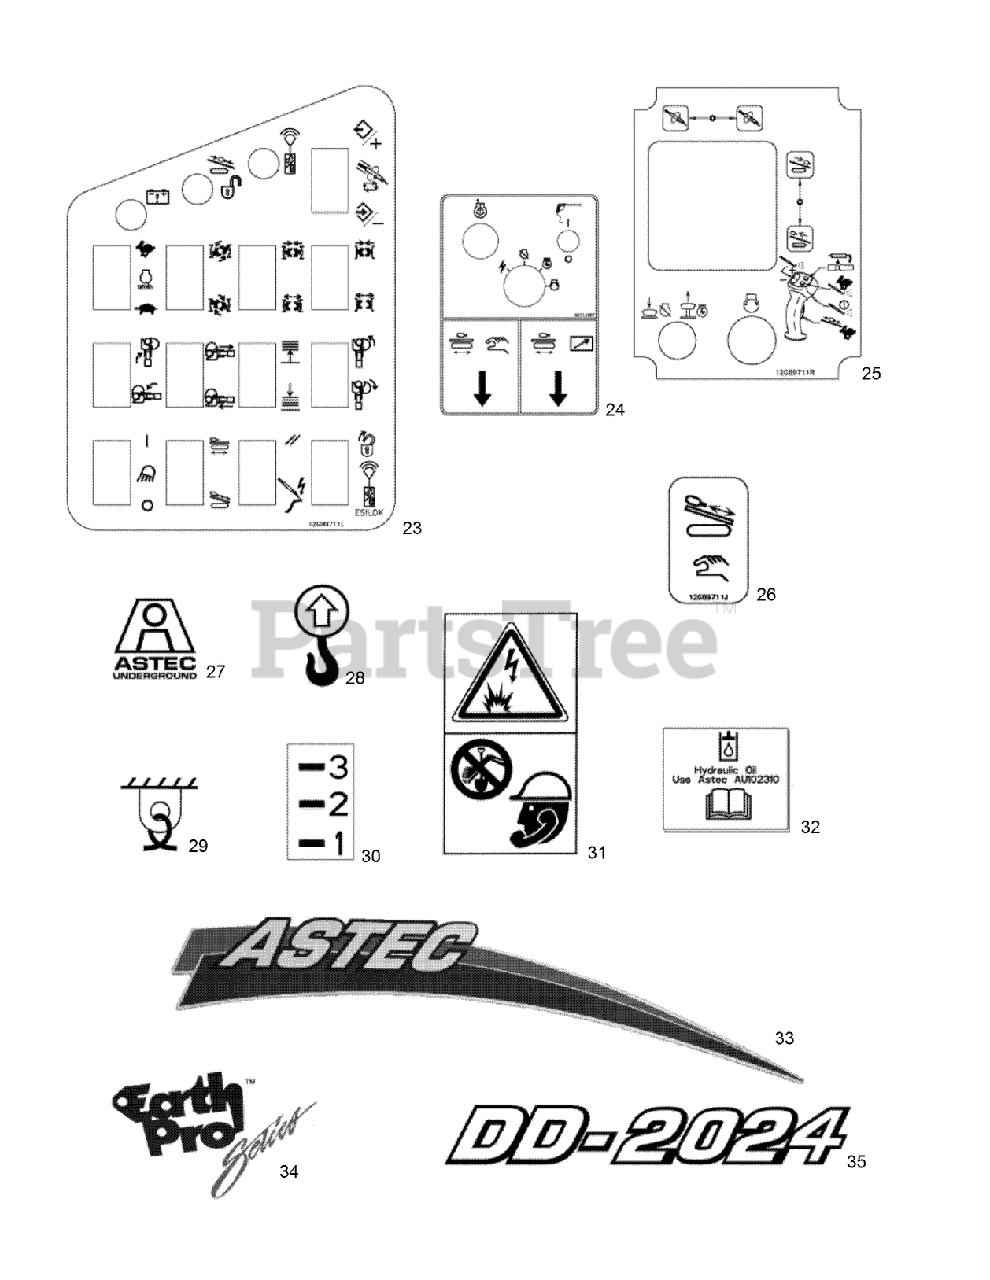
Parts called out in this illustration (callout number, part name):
24	OVERLAY - Rear Controls
25	DECAL - Joystick Overlay
26	DECAL - Remote Plug
27	DECAL - A, Astec Underground
28	DECAL - Lift Hook Location
29	DECAL-Tie Down
30	DECAL - Row Selector
31	DECAL - Call Before You Dig, ISO
32	DECAL - Hydraulic Fluid.
33	DECAL - Astec, Red and Blue Pattern
34	DECAL - Earth Pro, Medium Size
35	DECAL - DD-2024
